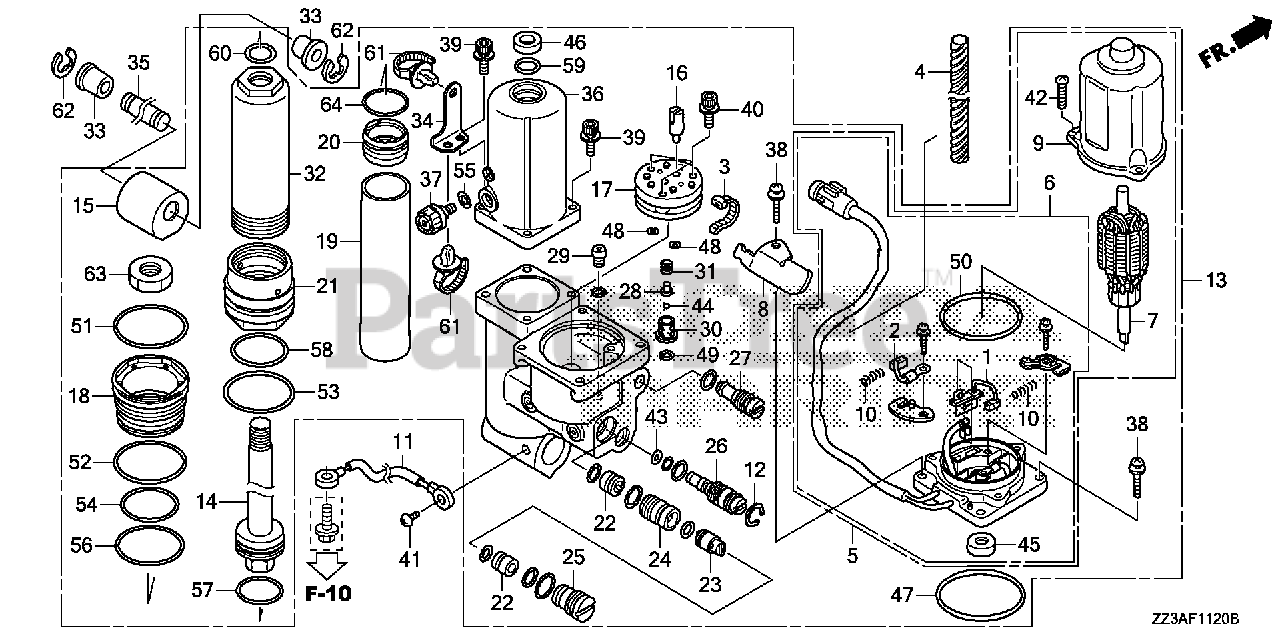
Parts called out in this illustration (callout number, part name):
1	BREAKER ASSY.
2	BRUSH ASSY.
3	BAND (BLACK 3.5X140)
4	TUBE, SPIRAL (12X14.6)
5	MOTOR ASSY., POWER TILT
6	BRACKET ASSY.
8	CLAMP, WIRE
10	SPRING, MOTOR
11	WIRE, LEAD (1.5X116MM)
12	CIRCLIP (INNER) (16)
13	TRIM-TILT ASSY., POWER
14	ROD, PISTON
15	METAL, JOINT
16	JOINT, DRIVE
18	GUIDE, TUBE (OUTER)
19	CYLINDER, TILT
21	LOWER TILT CYLINDER
26	VALVE, MANUAL
28	GUIDE, SPRING
30	SEAT B, VALVE
31	SPRING, VALVE
32	TUBE (OUTER)
33	BUSH, CYLINDER (UPPER)
34	PLATE, SET
35	PIN, CYLINDER (UPPER)
37	CAP, OIL TANK
38	SCREW-WASHER
39	BOLT, SOCKET (5X0.8)
40	BOLT, SOCKET
41	SCREW, PAN (6X8)
42	SCREW, PAN (5X20)
43	WASHER, SEAL
44	BALL, STEEL
46	SEAL, WATER
47	O-RING (1.8X69.6)
48	O-RING (1.5X6.5)
49	O-RING (1.5X3.5)
50	O-RING (2.0X55.5)
51	O-RING (2.0X52.5)
52	O-RING (2.0X49.5)
53	O-RING (3.5X41.7)
54	O-RING (2.4X41.2)
55	O-RING (1.8X10.8)
56	O-RING (2.0X45.5)
57	O-RING (2.0X28.5)
58	O-RING (2.0X34.5)
59	O-RING (1.9X15.8)
60	O-RING (2.4X15.8)
61	CLIP, HARNESS BAND (145MM) (BLACK)
62	E-RING (10MM)
63	NUT, JOINT METAL
